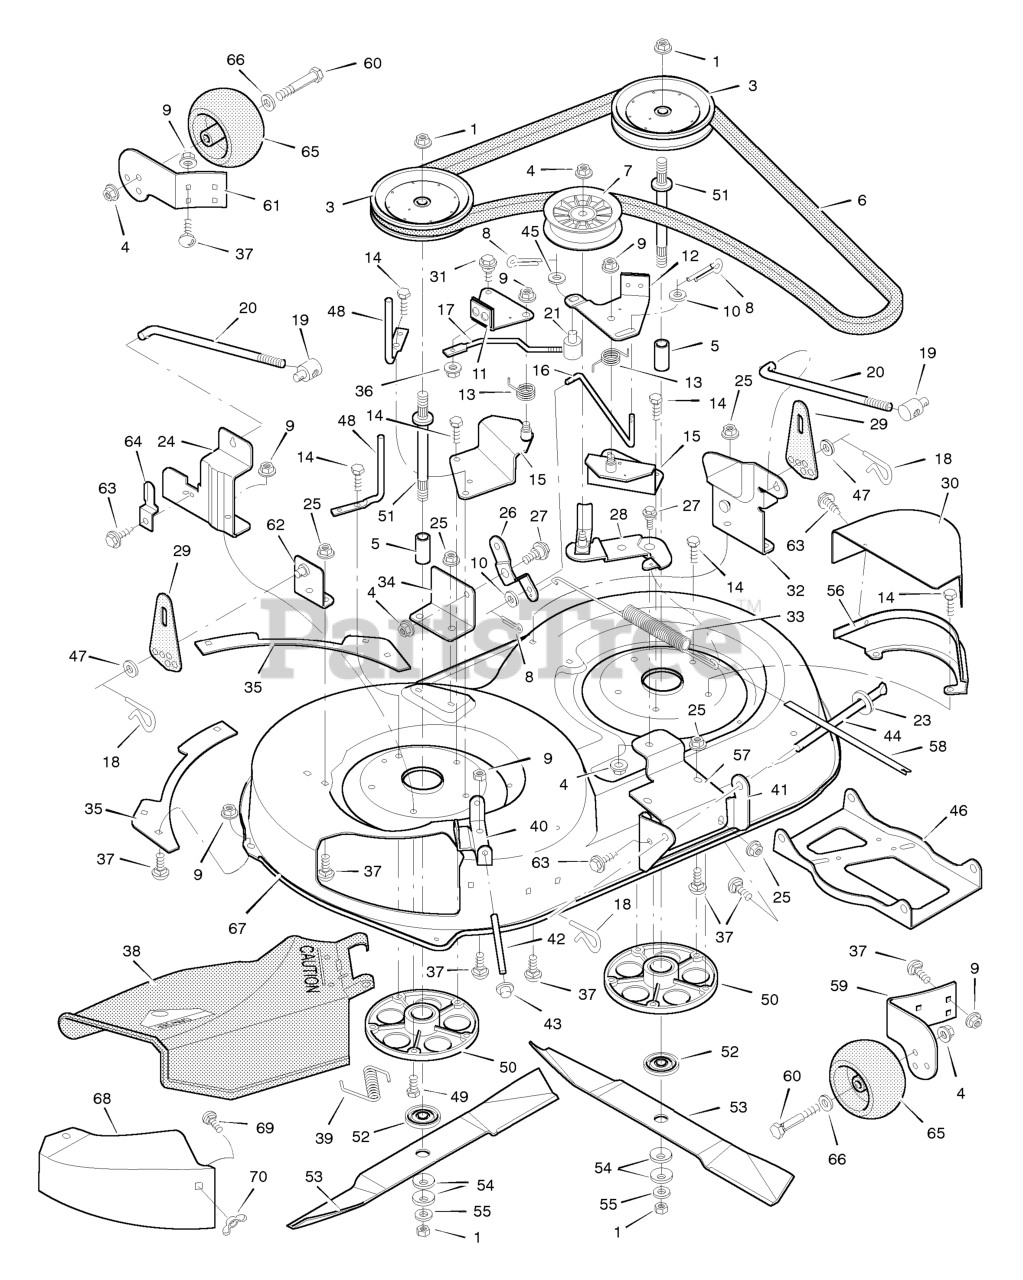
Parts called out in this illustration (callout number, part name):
1	Nut, Hex
3	Pulley, Jackshaft
4	Locknut, Flange
5	Spacer
6	Belt, Blade Drive
7	Pulley, Idler
8	Pin, Cotter
9	Locknut, Flange
10	Washer
11	Brake Assembly, Right
12	Brake Assembly, Left
13	Spring, Torsion
14	Bolt, Hex
15	Bracket Assembly, Brake
16	Rod, Brake
17	Rod, Cross Link
18	Pin, Hair
19	NUT, Adjusting, 1/2-13
20	Rod, Adjuster
21	Nut, Adjustable
24	Bracket, Right
25	Nut, Flange
26	Bracket, Pivot
27	Bolt, Carriage
28	Arm Assembly, Idler
29	Plate, Adjuster
30	Cover, Pulley
31	Bolt, Shoulder
32	Bracket Assembly, Left Lifter
33	Spring, Extension
34	Bracket, Pivot
36	Locknut, Flange
37	Bolt, Carriage
38	Deflector Assembly, Chute
39	Spring, Torsion
40	Bracket, Hinge
41	Bracket, Front Hanger
42	Rod, Deflector
43	Cap, Push On
44	Rod, Hanger
46	Hanger, Front
48	Rod, Belt Guide
49	Bolt, Hex
50	Housing, Jackshaft
51	Jackshaft
52	Adapter, Blade
53	Blade, 42" (Left)
54	Washer, Belleville
55	Washer
56	Bracket, Pulley Cover
57	Bracket, Idler Mount
58	Indicator, Plastic
59	Bracket, Right Wheel
60	BOLT, Gauge Wheel
61	Bracket, Left Wheel
62	Bracket Assembly, Right Lifter
64	Guide, Belt
65	Wheel, Gauge
66	Washer
67	Housing, Blade
68	Cover, Mulcher
69	Bolt, Carriage
70	Wingnut
